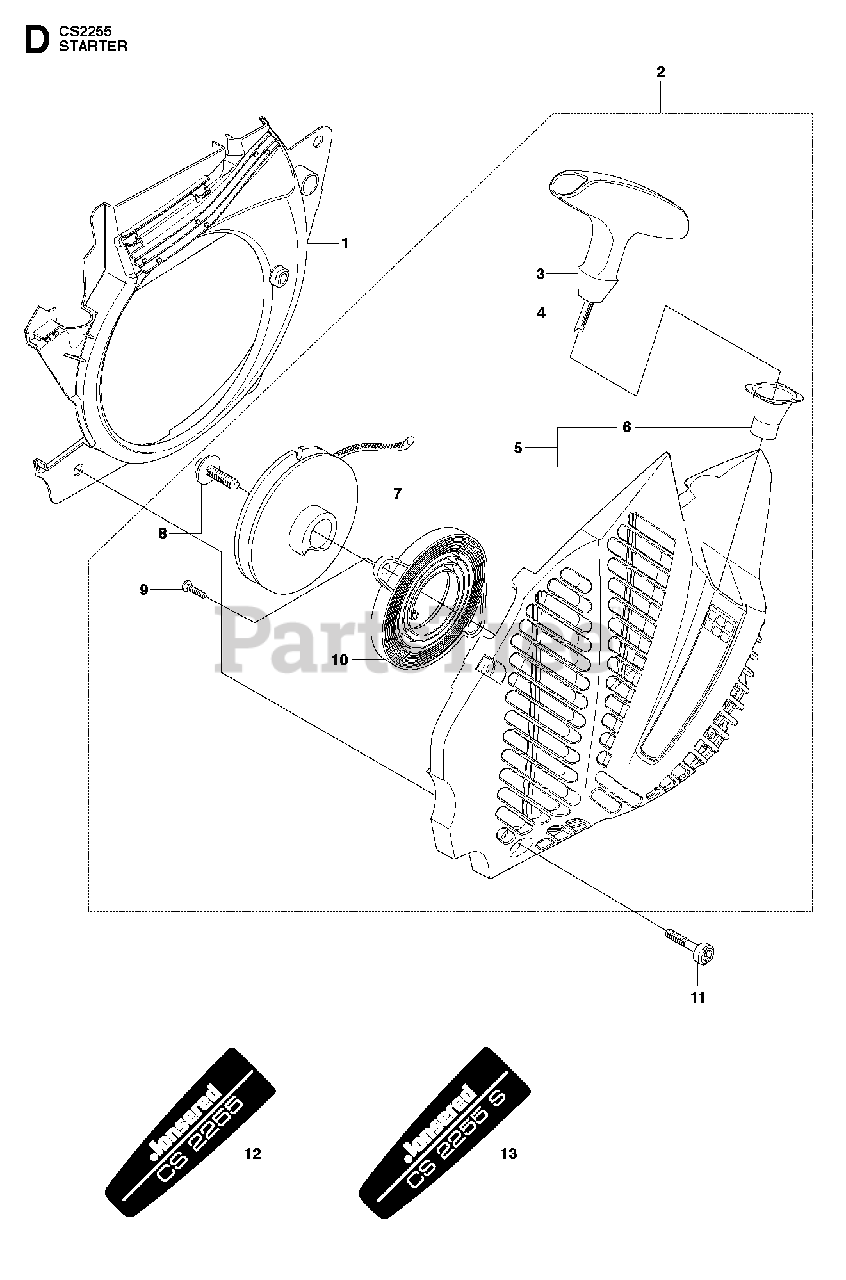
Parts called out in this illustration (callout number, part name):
1	AIR CONDUCTOR
2	STARTER ASSY
3	STARTER HANDLE
4	STARTER ROPE
5	STARTER HOUSING
6	SLEEVE
7	PULLEY
8	SCREW
9	SCREW
10	RETURN SPRING
12	DECAL
